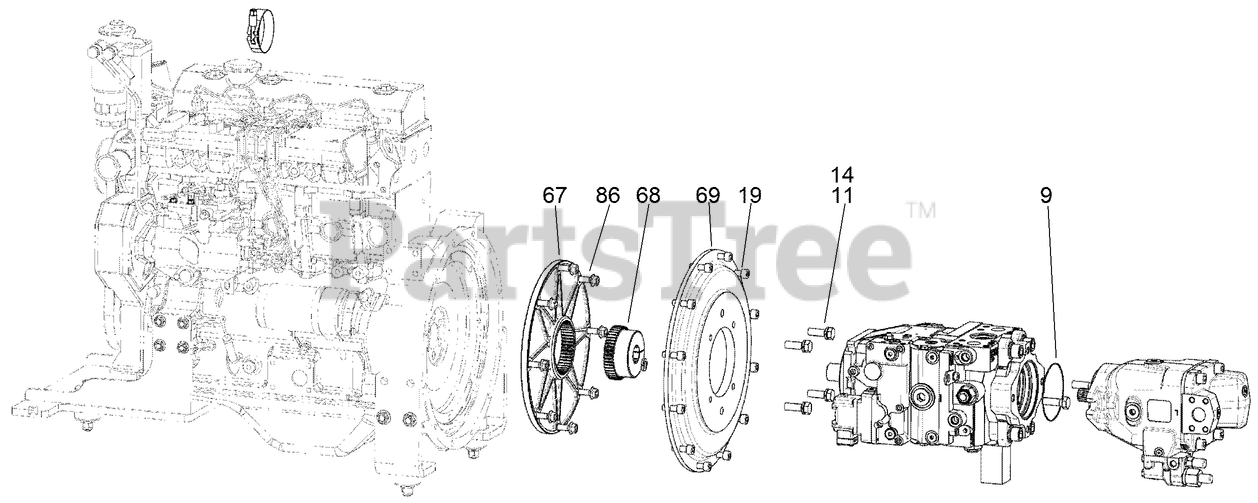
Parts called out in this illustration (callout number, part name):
9	O-RING - .062 x 4.00 in Class 5
11	SCREW-HH
14	WASHER-Spring Lock Reg 1/2 ZND
19	SCREW-HSH
67	COUPLING-DRIVE
68	HUB-STEEL
69	MOUNT - Pump
86	SCREW-HH
